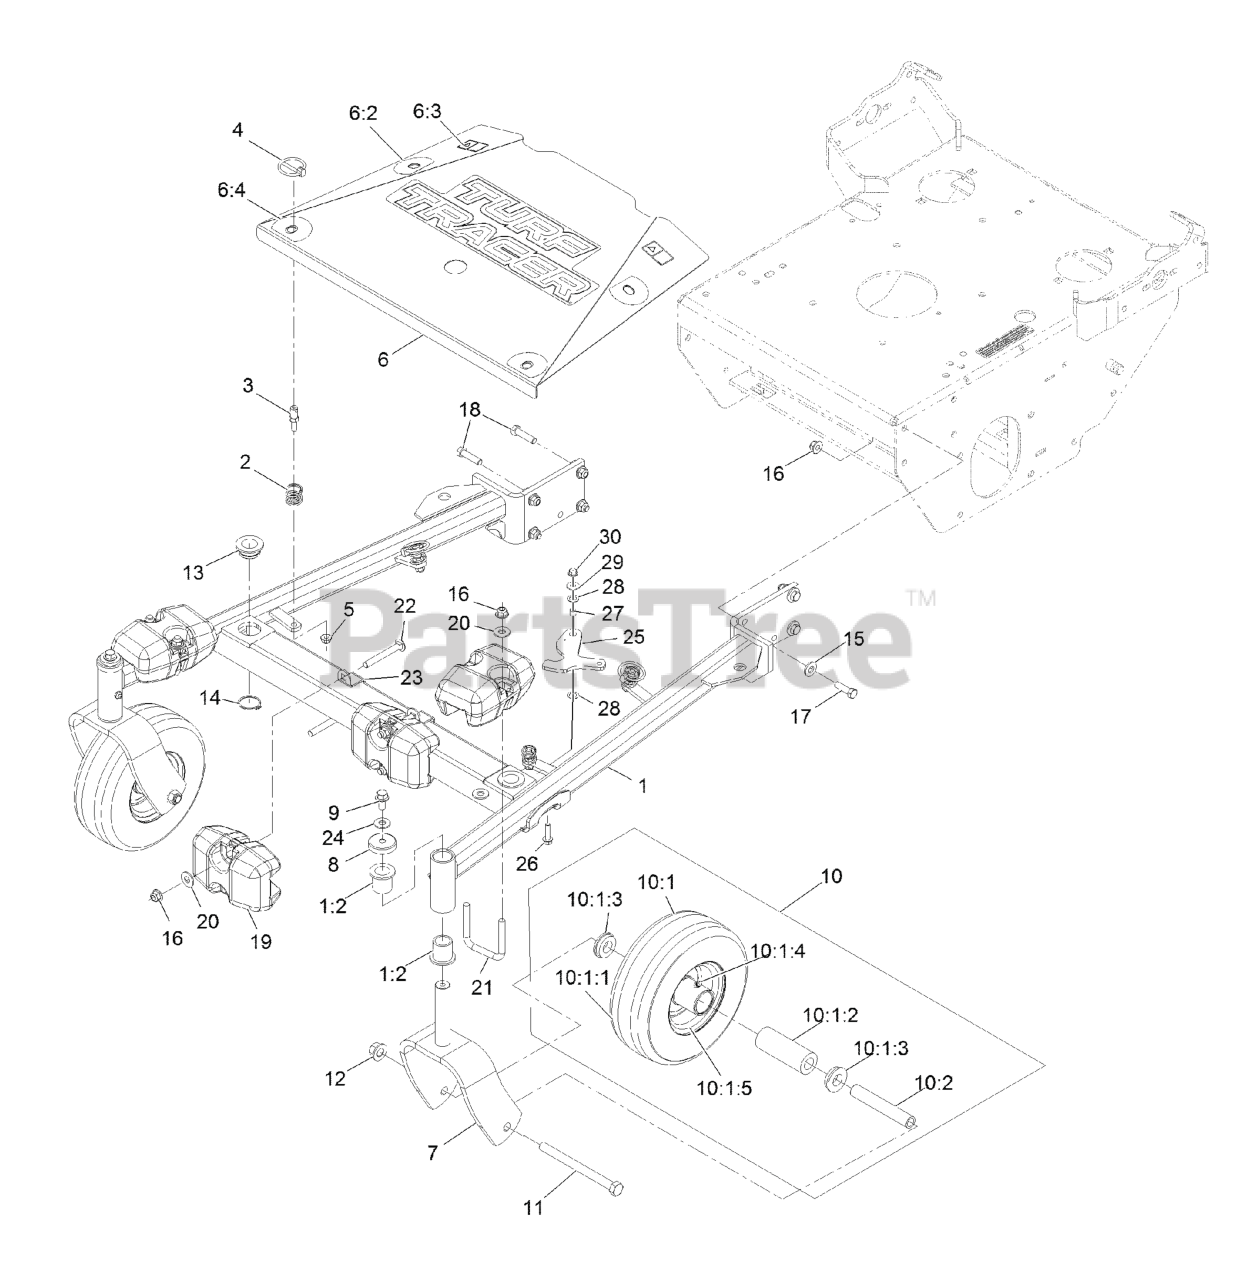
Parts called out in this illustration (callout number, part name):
1	ASM, FRAME W/ BUSHINGS, 4
1:2	BEARING-FLANGED
3	PIN-SPRING
4	PIN-LYNCH
5	NUT-HF, NI
6	ASM, SHIELD W/ DECALS, 48
6:2	DECAL-TURF TRACER
6:3	DECAL-WARNING
6:4	DECAL-SCRATCH COVER
7	FORK, CASTER
8	CAP, DUST
9	SCREW-HHF
10	KIT, SP CASTER WHEEL REPL
10:1	Wheel And Tire ASM
10:1:1	Tire
10:1:2	BEARING
10:1:3	BUSHING
10:1:4	FITTING-GREASE
10:1:5	Wheel
11	SCREW-HH
12	Nut-Lock 1/2-13
13	BUSHING-DECK
14	RING-RETAINING
15	WASHER-BELLEVILLE
16	NUT-HF, NI
17	SCREW-HH
18	SCREW-HH
19	WEIGHT-SUPPORT, CASTER
20	WASHER-FLAT
22	SCREW-CARR
23	STRAP, WEIGHT
25	LATCH, DECK HEIGHT
26	Screw-HHF
27	Spacer-Grommet
28	WASHER-CONICAL
29	WASHER-FLAT
30	NUT-HF, NI
